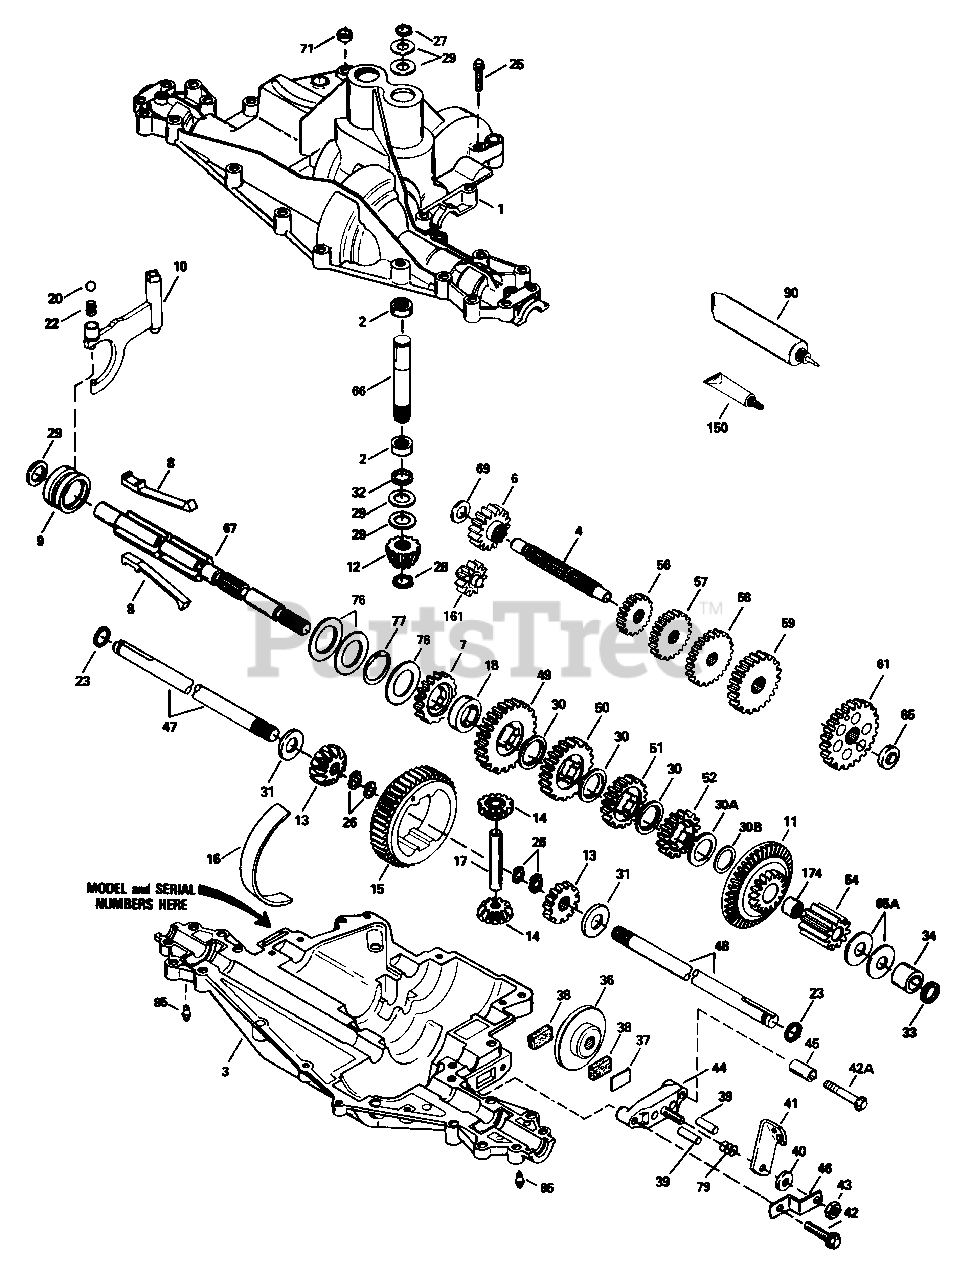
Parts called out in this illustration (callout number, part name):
1	COVER, Transaxle
2	BEARING, Needle
3	CASE, Transaxle
4	COUNTERSHAFT, (4-7/8" Long)
6	GEAR, Spur (16 Teeth)
7	GEAR, Spur (22 Teeth)
9	COLLAR, Shifter
10	ROD & FORK ASSY., Shift
11	GEAR, Bevel (44 & 16 Teeth)
12	BEVEL PINION, Input
13	GEAR, Bevel
14	GEAR, Bevel Pinion
15	RING GEAR
16	STRIP, Bearing
17	PIN, Drive
18	SPACER, Neutral (1-3/8" O.D. x 1-1/8" I.D. x 15/32" Thick)
20	BALL, Steel
23	SEAL RING
25	SCREW, Hex Hd., Flange, Threadforming, 1/4-20 x 1-1/4
26	RING, Retaining, (Pkg. of 2)
27	RING, Retaining
28	RING, Retaining
29	WASHER, Thrust
30	WASHER, Thrust
30A	WASHER, Thrust
30B	WASHER, Thrust
33	SEAL, Square Cut
36	DISK, Brake
37	PLATE, Brake Pad
38	PAD, Brake (Pkg. of 2)
39	PIN, Dowel
40	WASHER, Flat
41	LEVER, Brake
42	SCREW, Hex Hd., Flange, Threadforming, 1/4-20 x 1-1/4
42A	SCREW, Hex Hd., Flange, Threadforming, 1/4-20 x 2-1/4
43	NUT, Lock, 5/16-24
44	HOLDER, Brake Pad
46	BRACKET, Brake Lever
47	AxLE, (16-7/8" Long)
48	AxLE, (11-5/8" Long) (Incl. Ref. No. 26, Qty. 2))
49	GEAR, Spur (35 Teeth)
50	GEAR, Spur (27 Teeth)
51	GEAR, Spur (22 Teeth)
52	GEAR, Spur (19 Teeth)
54	GEAR, Spur (11 Teeth)
56	GEAR, Spur (15 Teeth)
57	GEAR, Spur (23 Teeth)
58	GEAR, Spur (28 Teeth)
59	GEAR, Spur (30 Teeth)
61	GEAR, Spur (34 Teeth)
65	WASHER, Thrust
65A	WASHER, Thrust
66	SHAFT, Input (3-5/16" Long)
67	SHAFT, Brake (4 Keyed)
69	WASHER, Thrust
71	SEAL, Square Cut
77	RING, Retaining, Inverted
79	SPRING, Brake
85	FITTING, Lubrication
90	GREASE, 32 oz. Bottle
150	GASKET ELIMINATOR (Loctite #515)
161	IDLER ASSY., Reverse
174	BEARING, Needle
